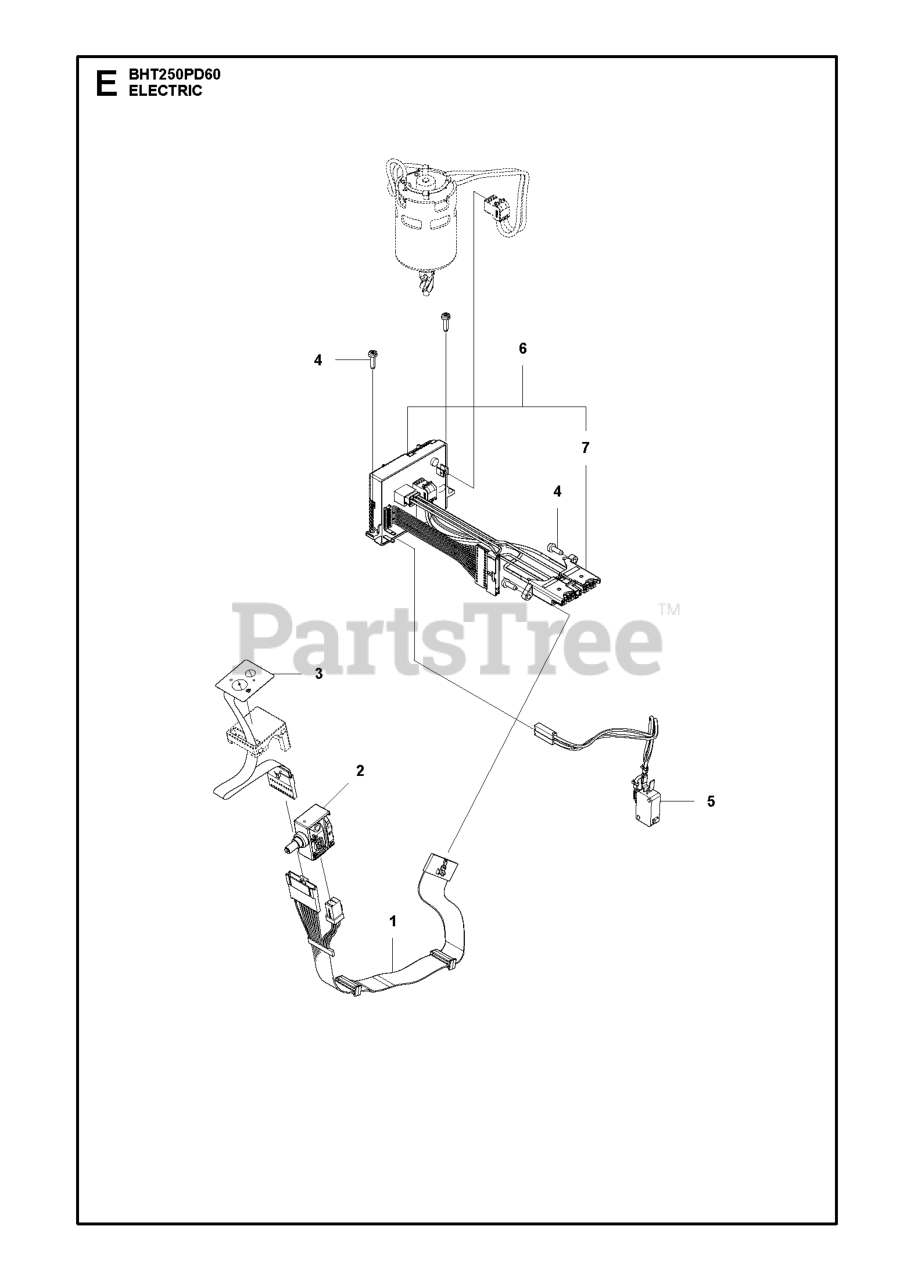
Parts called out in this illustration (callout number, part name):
1	WIRING ASSY TRIGGER HANDLE
2	TRIGGER SWITCH IPX4
3	KEYPAD 2 BUTTON MEMCON CONNECT
4	SCREW CCRPANT
5	WIRING ASSY FRONT GUARD
6	CONTROL UNIT PMDC SAFE HEDGE T
7	CONNECTOR BATTERY
